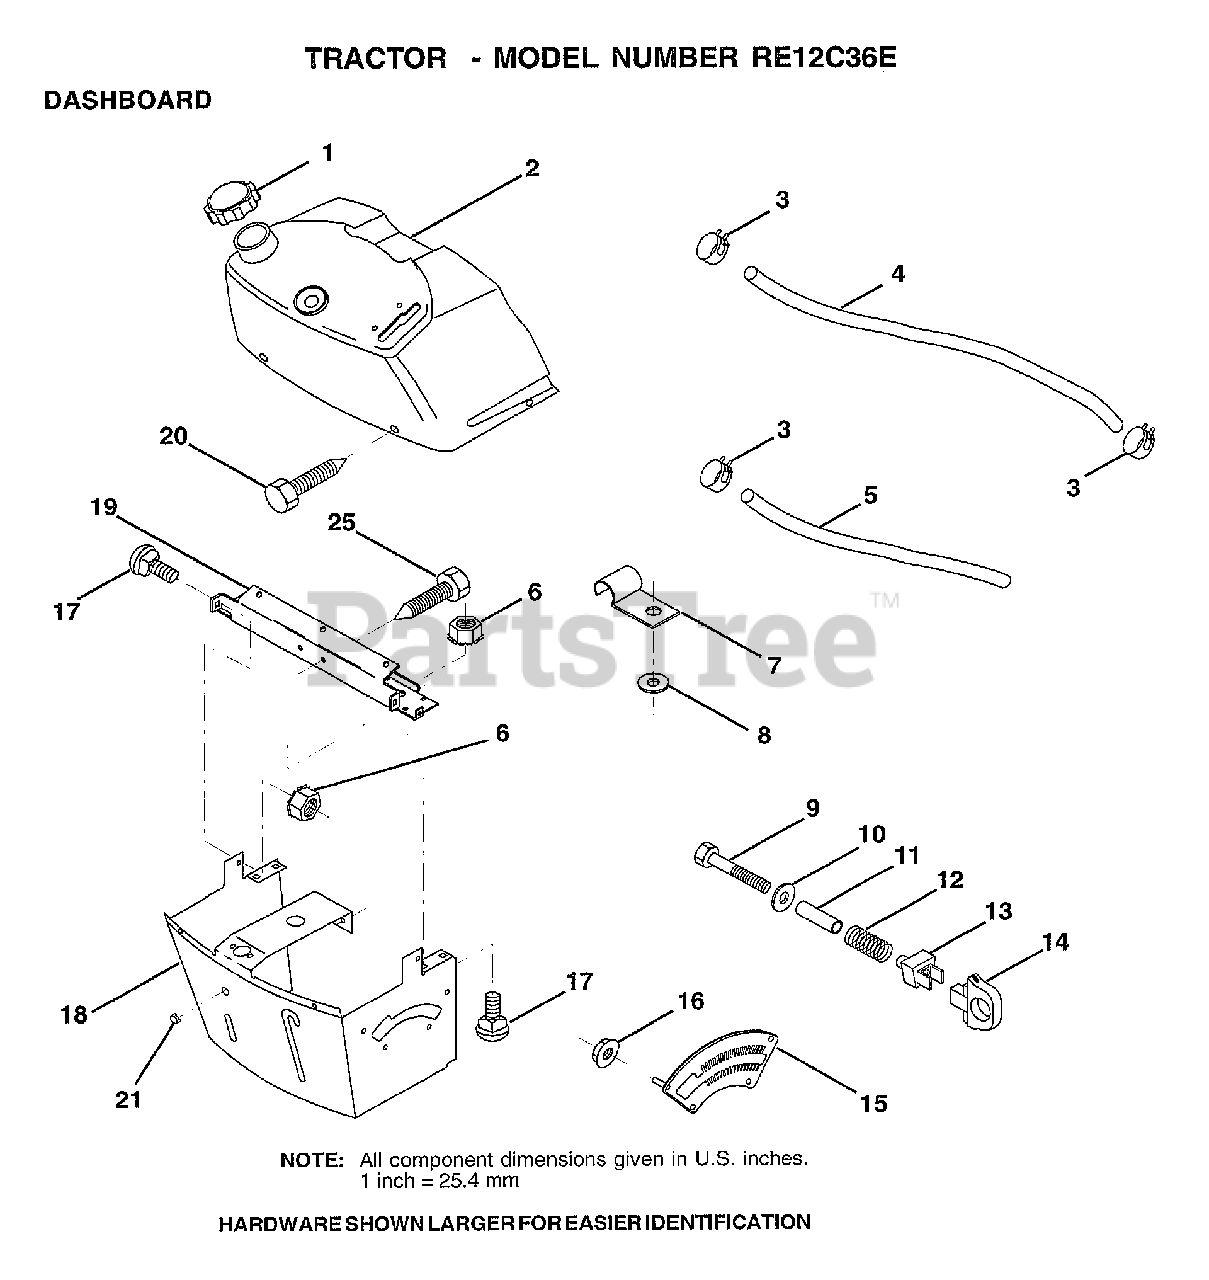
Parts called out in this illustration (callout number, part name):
1	CAP BLK FUEL LR
2	TANK.ASM.DASH.LR
3	HOSE CLAMP
5	FUEL LINE T
6	NUT HXKEP 1/4X20
7	CLIP T
8	WASHER PM
9	BOLT
11	SPACER SPLIT
12	SPRING M
13	"KNOB,HGT RETAINER"
14	KNOB
15	ADJUSTER QUAD
16	NUT
17	BOLT
18	SUPT ASSY DASH
19	CROSS BRACE
20	SCREW.1/4-20X1/2
21	PLUG DOME
25	SCREW LT
